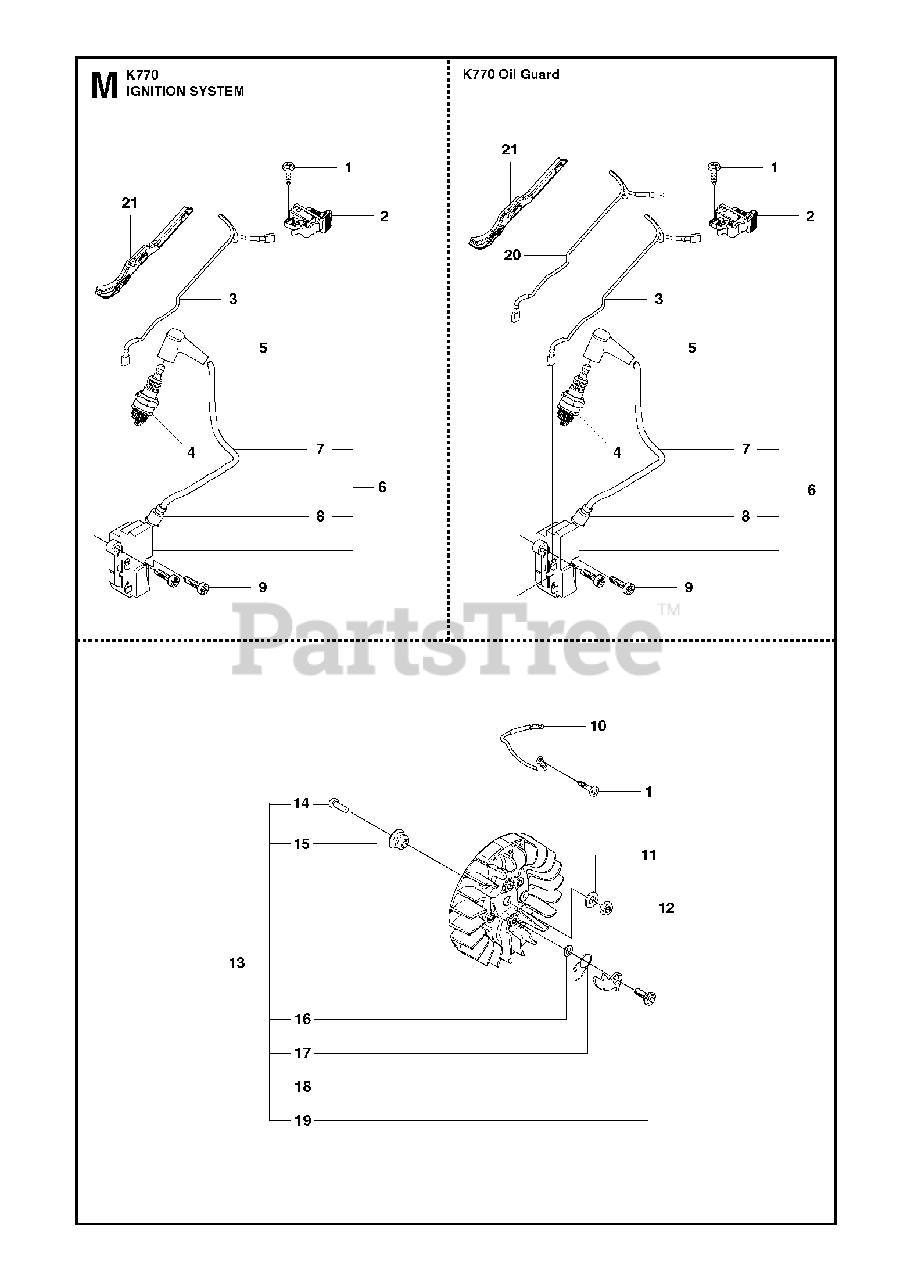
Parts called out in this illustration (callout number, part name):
1	SCREW CITXPANT
4	SPARK PLUGRCJ 6 Y
5	SPARK PLUG CAP
6	IGNITION MODULEIncl. 5, 7 - 8
7	IGNITION CABLE
9	SCREW ITXSCM
12	HEXAGON NUTIncl. 14 - 19
14	SCREW IHSCM
19	SCREW
20	CABLEOil Guard
21	CABLE HOLDER
